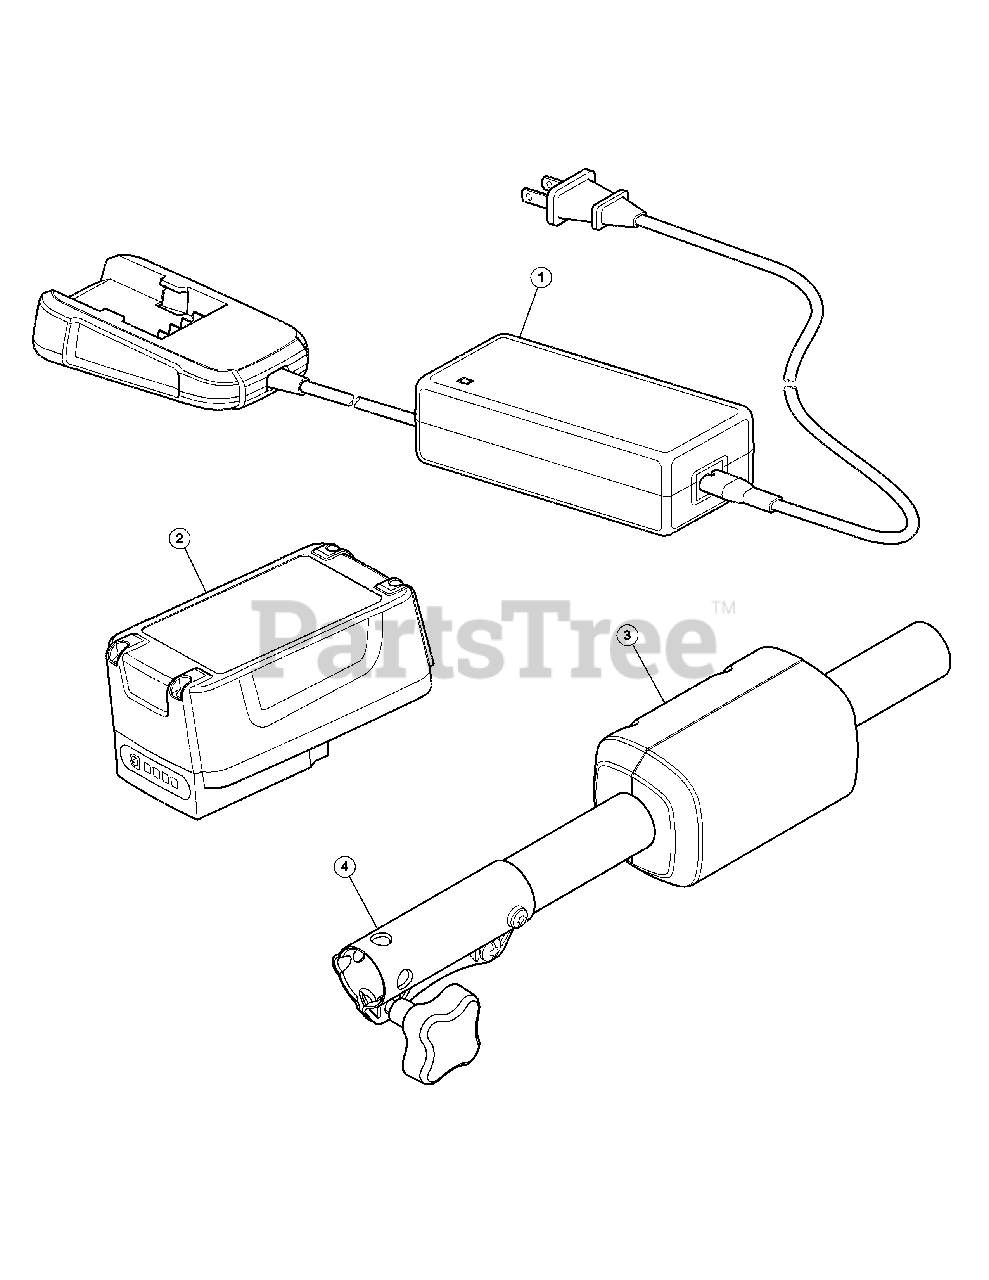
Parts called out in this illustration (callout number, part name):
1	Charger
2	Battery
3	Extension Boom (inc .4)
4	Split Boom Coupler
